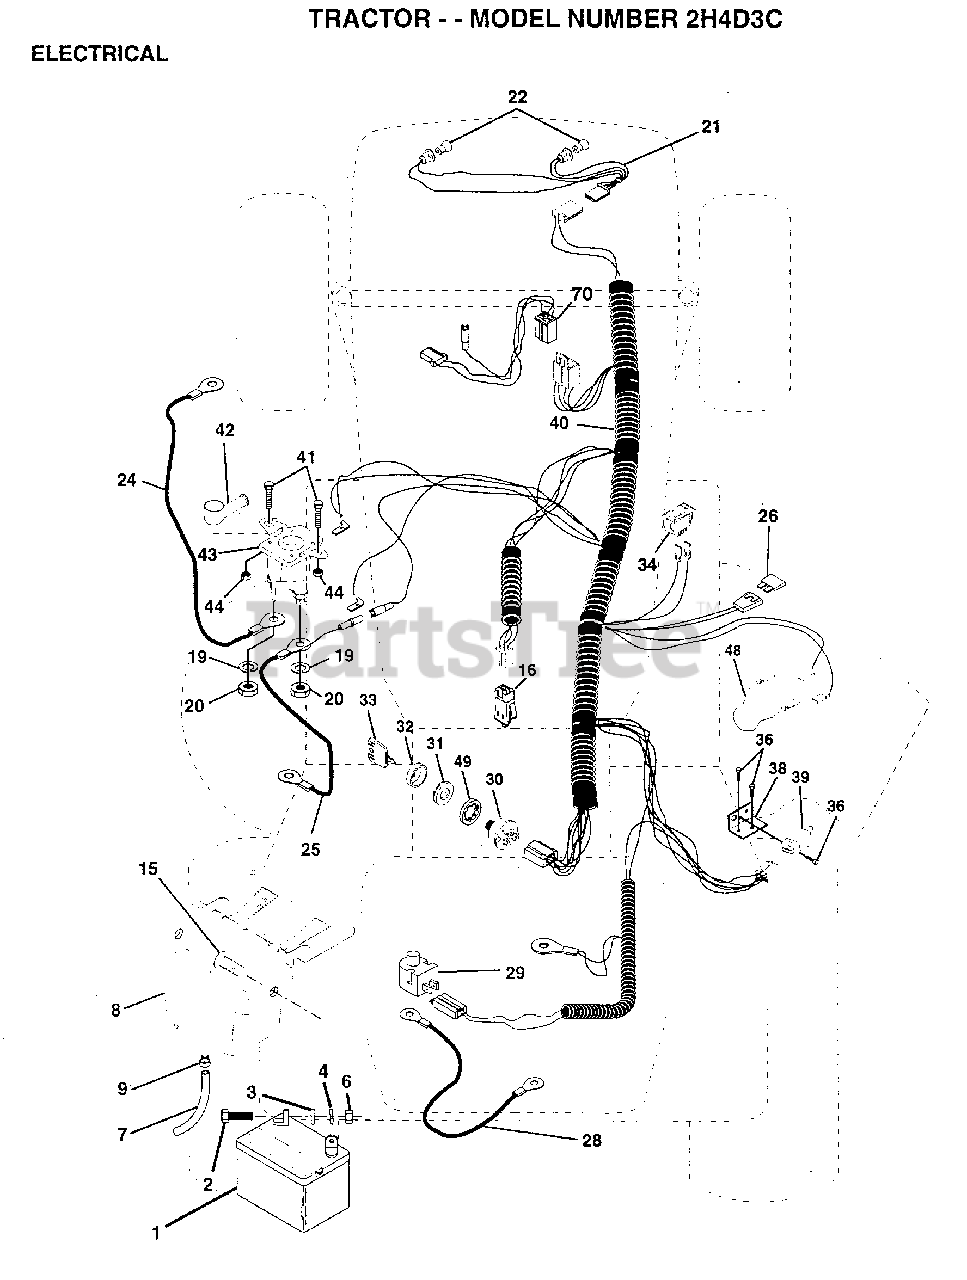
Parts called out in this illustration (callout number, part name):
2	BOLT LT
3	WASHER
4	LOCKWASHER
7	TUBE T
9	HOSE CLAMP T
15	FASTNER.SNAP-IN
16	SWITCH INTERLOCK
20	NUT
21	"HARNESS,LIGHT SOC"
22	HEADLAMP BULB
24	CABLE.BTRY.6GA.RD
25	CABLE.BTRY.6GA.38
26	FUSE HYT
28	CABLE T
29	SWITCH SEAT
32	COVER KEY SWITCH
33	KEY MLD GEN DELTA
34	SWITCH LT
36	SCREW
38	BRACKET SWITCH IN
39	SWITCH INTERLOCKT
40	HARNESS.IGN.DASH.
41	BOLT HXHD FIN
44	NUT HXKEP 1/4X20
48	ADAPTER AMMETER
49	WASHER PINNED
70	HARNESS ENG DUAL
